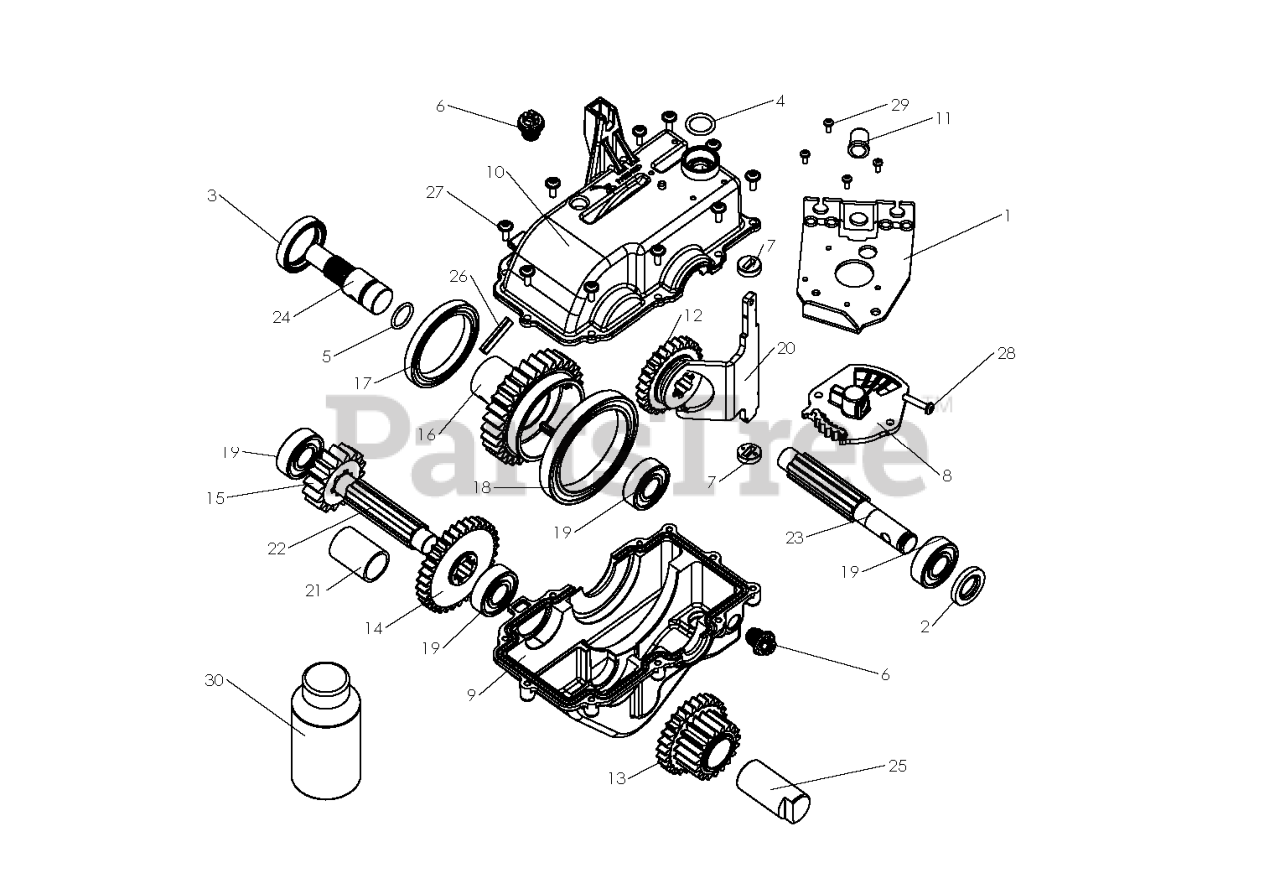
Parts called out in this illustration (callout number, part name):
11	SPRING BALL
17	BALL BEARING 6810
18	BALL BEARING 6813
19	BALL BEARING
